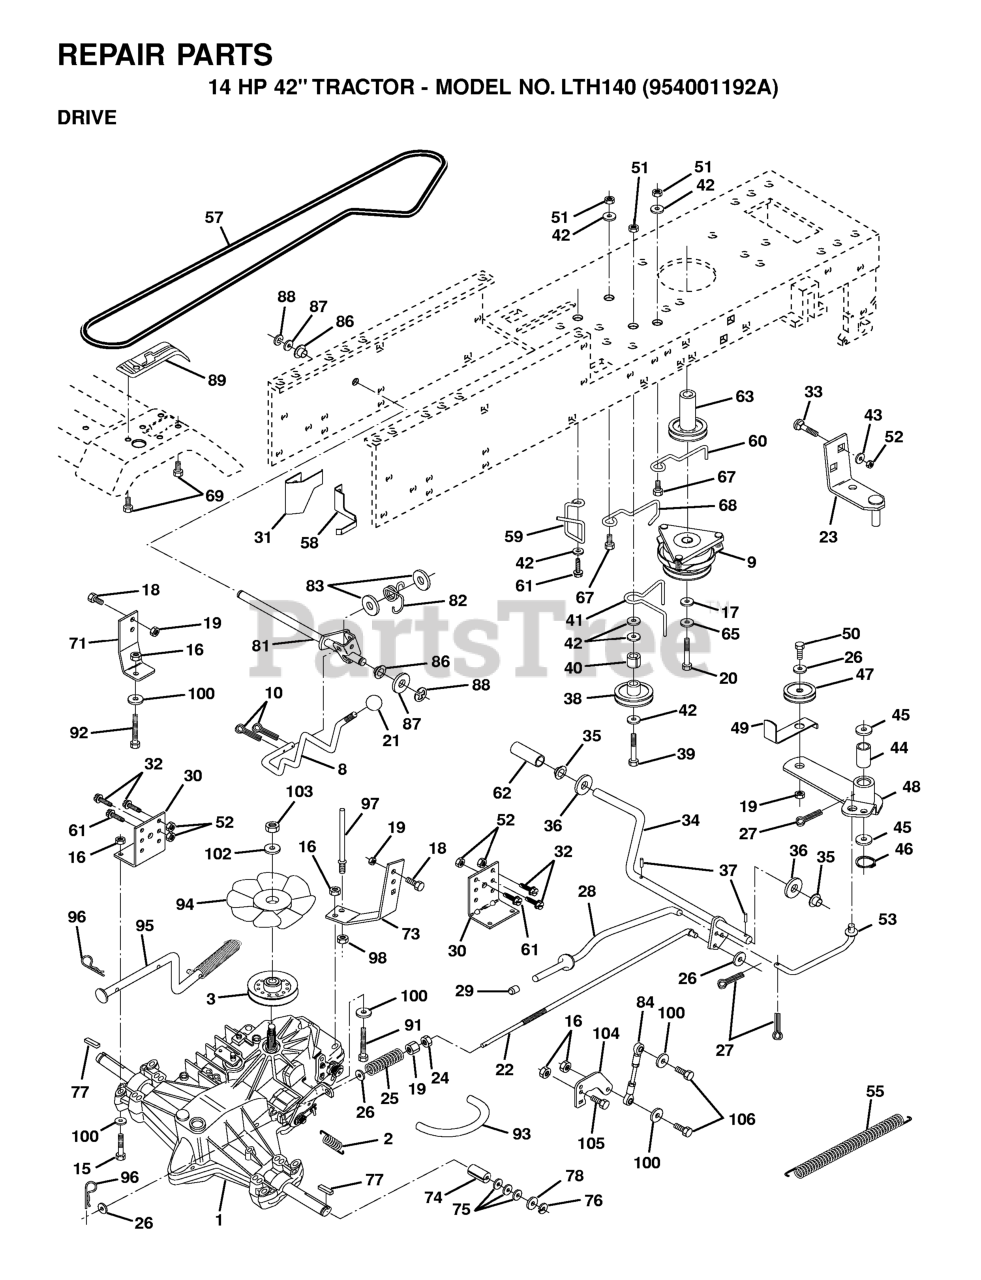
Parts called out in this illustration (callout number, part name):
1	TRANSAXLE ASMBLY
2	SPRING BRAKE
3	PULLEY, TRANSAXLE
9	CLUTCH.ELECT.CVX.105 FT/LB.
10	PIN COTTER
16	NUT.71038.31-18.HEX.NYLOCK
19	NUT
20	BOLT HEX
21	KNOB.DELUXE.(PISTOL.GRIP).BLAC
22	ROD BRAKE
23	BRACKET ASM MTG
24	NUT
25	SPRING ROD LT
26	WASHER
27	COTTER PIN
28	BRAKE PARK ROD
29	PLUNGER CAP
30	BRACKET TRANSAXLE
31	KEEPER BELT LH
32	BOLT
33	RP BOLT 5/16-18 X3/4 ZN/YEL GR
34	SHAFT FOOT PEDAL
35	BEARING.NYLON
37	DRIVE PIN
38	PULLEY.IDLER.FLAT
41	BELT KEEPER LT NLA
42	WASHER
44	BEARING LT (2 2)
47	IDLER PULLEY
49	RETAIN BELT
50	BOLT
52	LOCKNUT
53	LINK, CLUTCH LT
55	SPRING, RETURN LT
57	DRIVE BELT, LTH & YTH TRACTORS
58	KEEPER BELT LH
59	KEEPER CENTER SPAN
60	KEEPER BELT ENGLH
61	SCREW
62	COVER, PEDAL (1 2)
63	PULLEY CLU ELEC
65	LOCKWASHER
67	BOLT
68	KEEPER,BLT ENG LT
69	SCREW.HI-LO.CONSOLE
71	STRAP LH TORQUE
73	STRAP RH TORQUE
74	SPACER SPLIT
77	SQUARE KEY
81	SHAFT ASSY
82	SPRING,TORSION
83	WASHER
84	ROD.TIE.BALL.4.75
86	BUSHING.STEERING.ROD LTB-WSL
89	CONSOLE HYDRO LT
91	BOLT.FIN HEX 5/16-18UNC X2 1/4
92	HEX BOLT
93	LINE FUEL HYD 4"
94	FAN 7" HYDRO
95	CONTROL ARM, BYPASS HYDRO
96	RETAINER M
97	KEEPER BELT RH
100	WASHER M
104	CONTROL ARM
106	BOLT.5/16-18X1-1/4 FULL.THREAD
